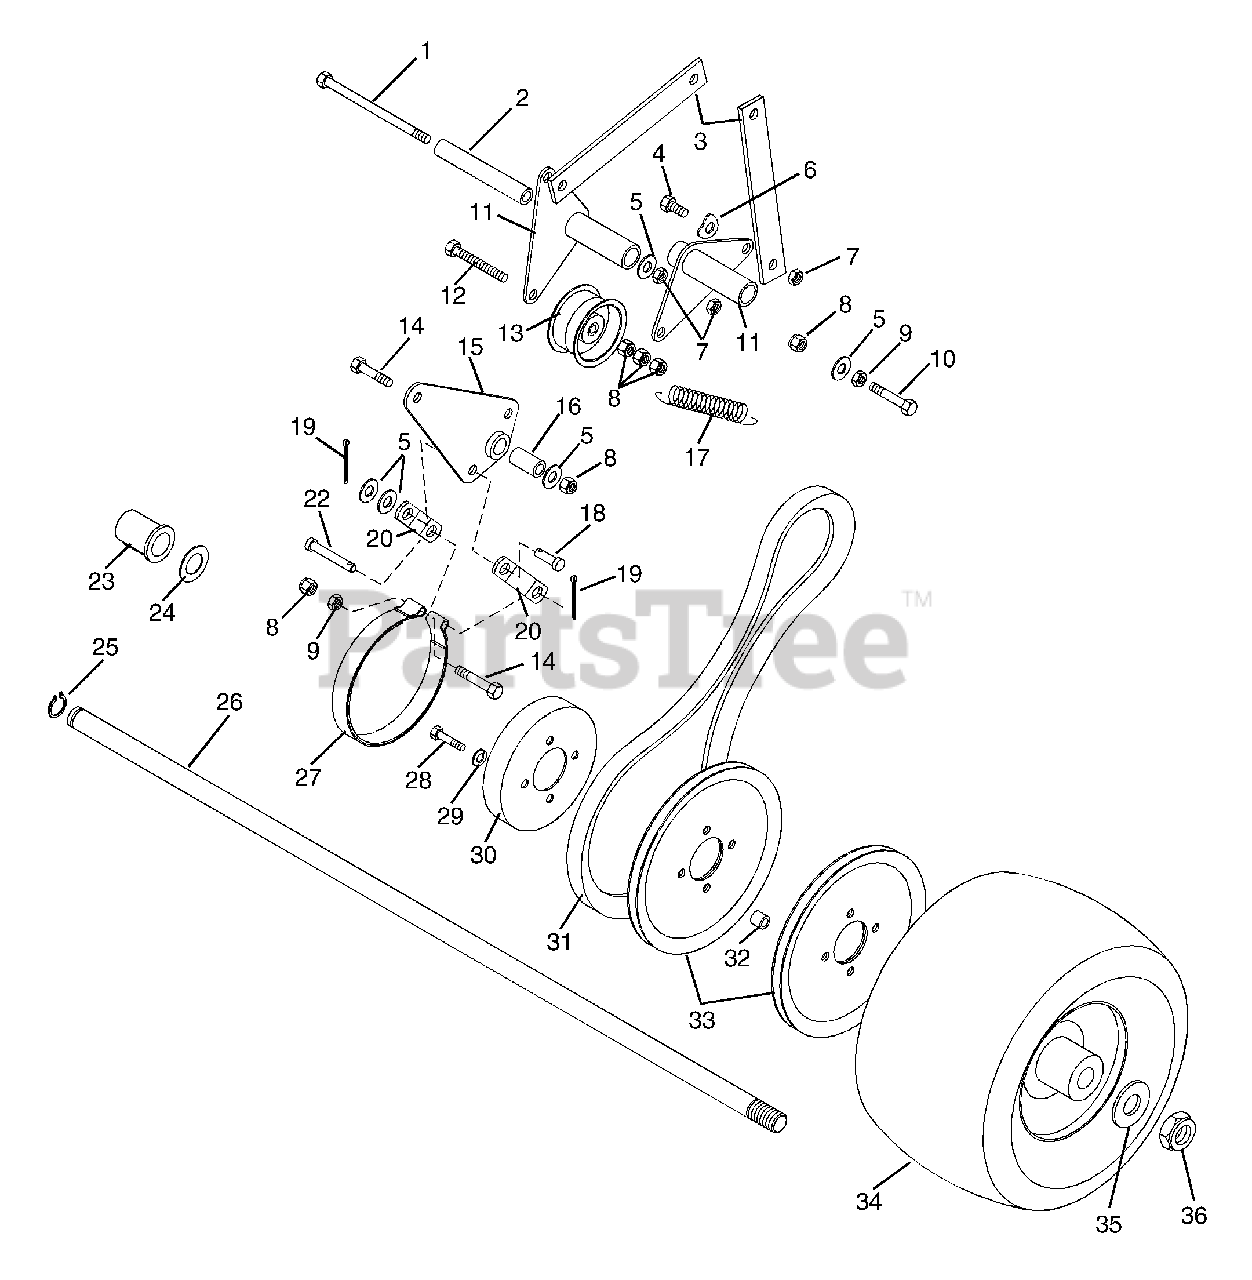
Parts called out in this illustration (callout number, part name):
1	Bolt-Hex .38-16 x 5.00
2	Bush, Steel .385 x .610 x 3.85
3	Strap, Wheel Clutch
4	Bolt-Hex .38-16 x .75 Grade 5
5	Washer-Flat-Steel .406 x .812 x .065
6	Washer-Spring .375
7	Nut-Locking-Center .625-10
8	Nut-Locking-Nylon .375-16
9	Nut-Hex .375-16
10	Bolt-Hex .38-16 x 2.25 Grade 5
11	Weldment, Wheel Clutch Arm
12	Bolt-Hex .38-16 x 3.0 Grade 5
13	Sheave 3.25 x 1.25
14	Bolt-Hex .38-16 x 2.00 Grade 5
15	Weldment, Brake Arm
16	Bushing, Sleeve .391 x .622 x .950
17	Spring-Tension .069 x .62 x 3.50
18	Pin-Clevis .38 x .75
19	Pin-Cotter .12 x .75
20	Link, Brake Arm
21	Nut, Locking 3/4 -10
22	Pin-Clevis .372 x 1.25
23	Bushing-Flange 1.010 x 1.38 x 1.4 x 1.65
24	Washer-Thrust 1.55 x 1.002 x .093
25	Ring-Retaining-External .906 x .078
26	Shaft, Axle
27	Assembly, Brake Band, Pro
28	Bolt-Hex .31-18 x 1.50 Grade 5
29	Washer-Lock External .375 x .050
30	Drum, Brake
31	V-Belt, Wheel Drive Set (2)
32	Bushing, Sleeve .385 x .625 x .475
33	Pulley-V 9.00 x 3.75
34	Tire/Wheel Assembly 13 x 6.50-6
35	Washer-Flat-Steel .813 x 1.370 x .100
36	Nut-Locking-Center .75-10
